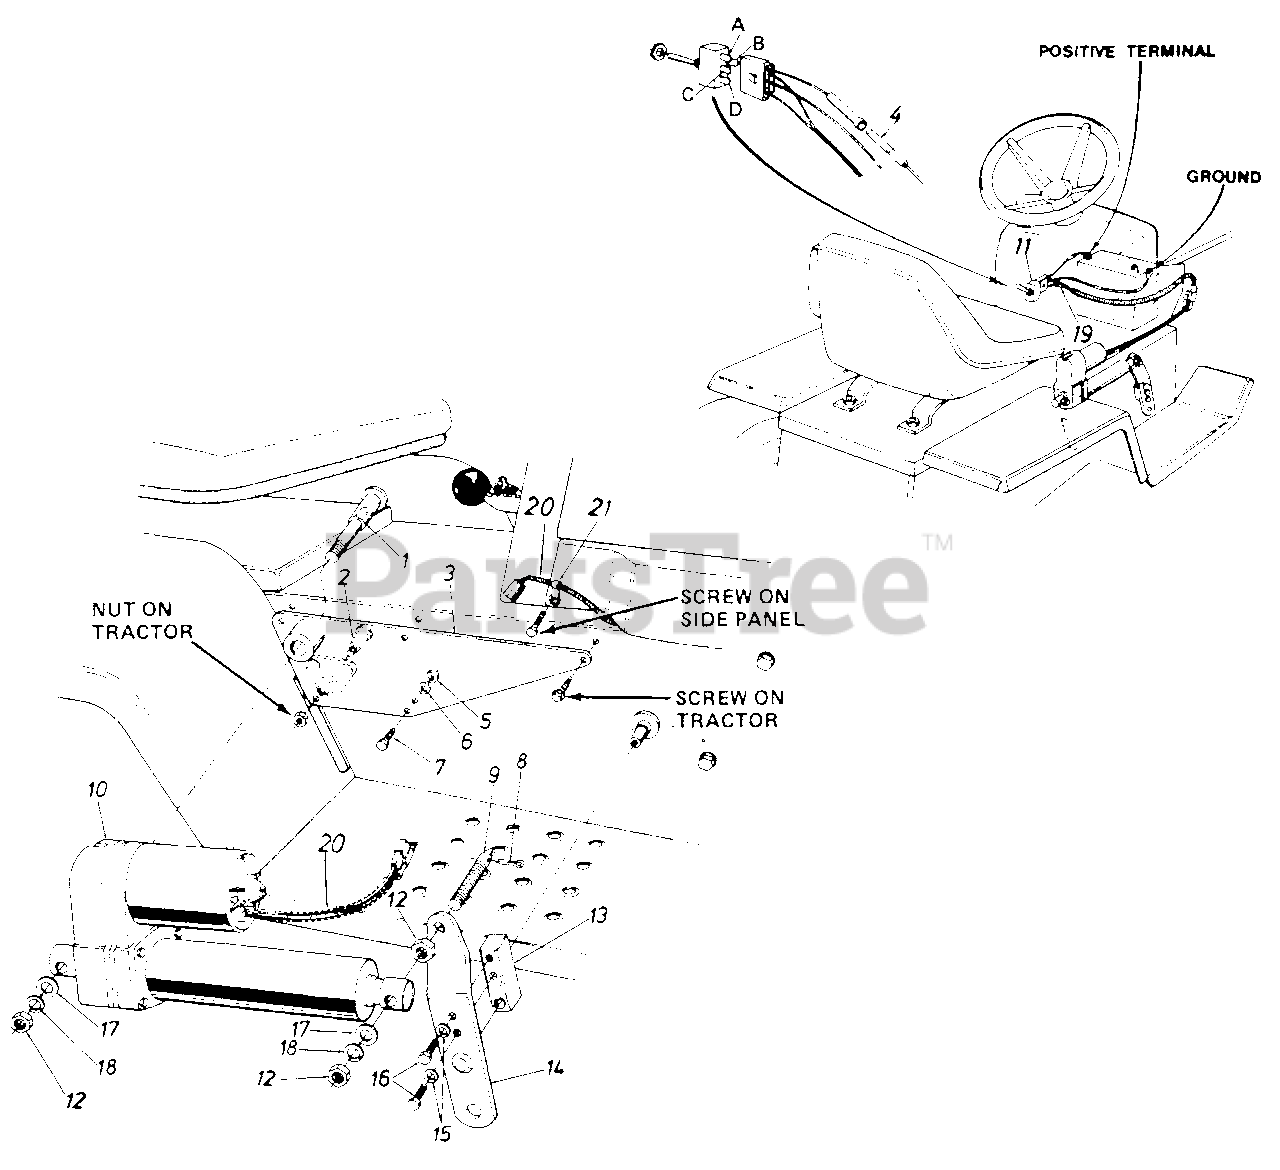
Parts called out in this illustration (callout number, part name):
1	Pivot Pin
2	Shld. Bolt.626 Dia. x .96"
3	Mtg. Plate Ass'y.
4	Fuse 30 AMP
5	Hex Nut 1/4-28 Thd.
6	L-Wash. 1/4" I.D.*
7	Hex Bolt 1/4-28 x .75" Lg.(Grade 5)
8	Coter Pin
9	Indicator & Mtg. Pin
10	Electric Actuator
11	Toggle Switch
12	Hex Jam Nut 1/2-13 Thd.
13	Lift Shaft Drive
16	Hex Bolt 5/16-24 x 1.0" Lg.(Grade 5)
17	Fl-Wash. .53" I.D. x .93" O.C.
18	L-Wash. 1/2" I.D.*
19	Wire Harness
20	Plastic Tubing-7"
21	Clamp
